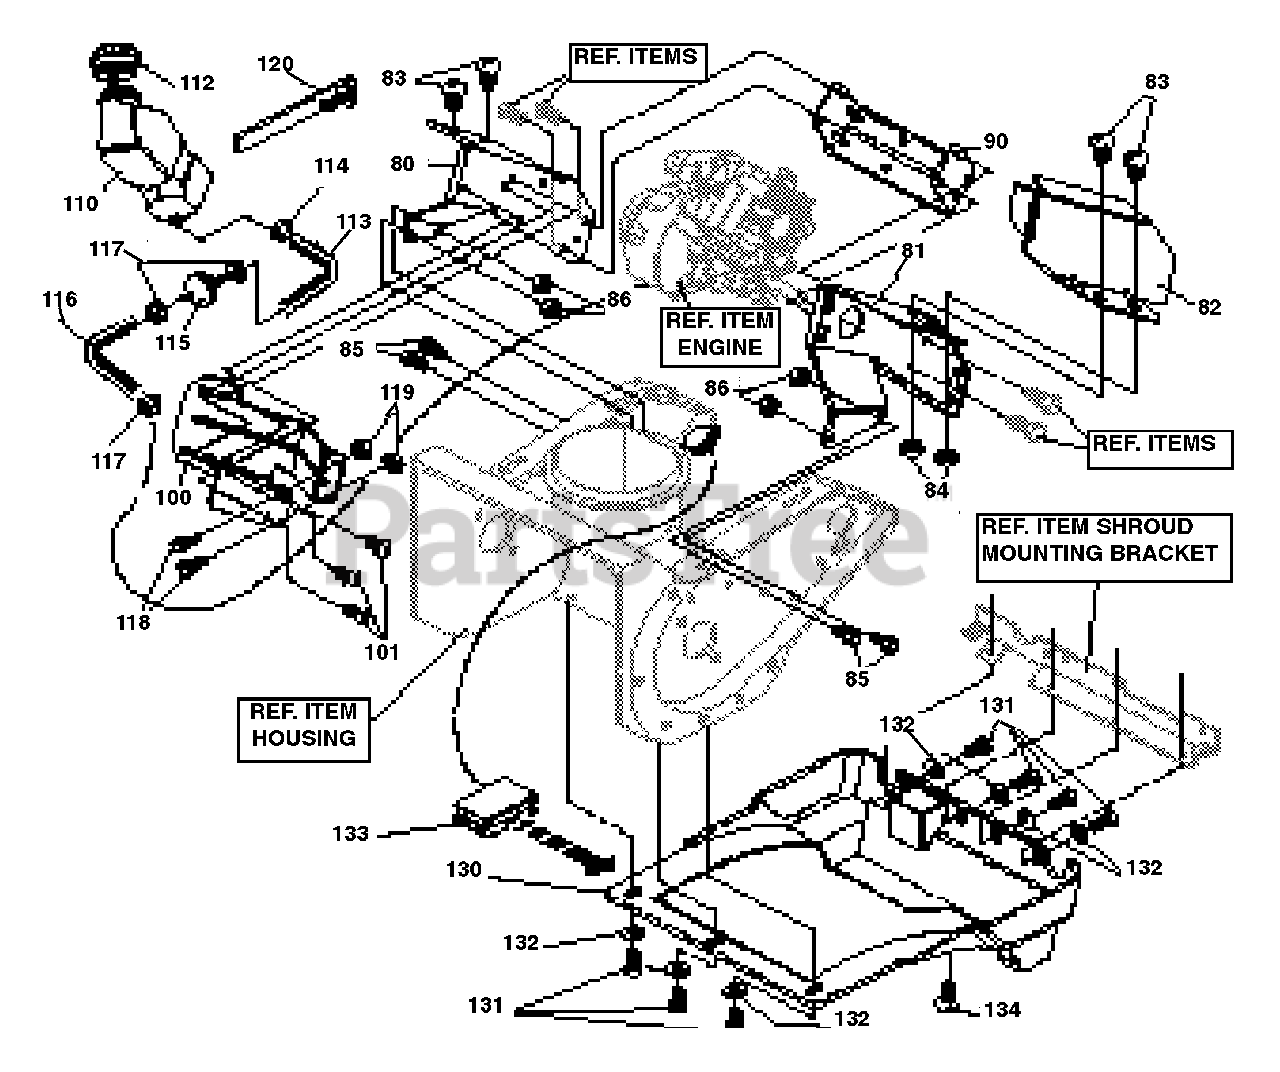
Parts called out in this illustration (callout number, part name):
80	PLATE, REAR RH
81	PLATE, REAR LH
82	SHIELD, ENGINE HEAT
83	SCREW, 1/4-20 X .63
84	NUT, 1/4-20 WDFL
85	SCREW, 5/16-18 X .50
86	NUT, 5/16-18
90	SUPPORT, FRAME
100	BRACKET, GAS TANK
101	SCREW, #10-24 X .63
110	TANK, FUEL
113	TUBING, .GAS LINE
114	CLAMP,HOSE
115	FILTER, IN-LINE
116	TUBING, .GAS LINE
117	CLAMP, HOSE
118	SCREW, 10-24 X .50
119	NUT, #10-24
120	CLAMP, WORM
130	COVER, BOTTOM
131	SCREW, #10-24 X .63
132	WASHER, FLAT .203 X .56 X .04O
133	CLIP, "S" TINNERMAN
134	SCREW, 10-16 X .50
